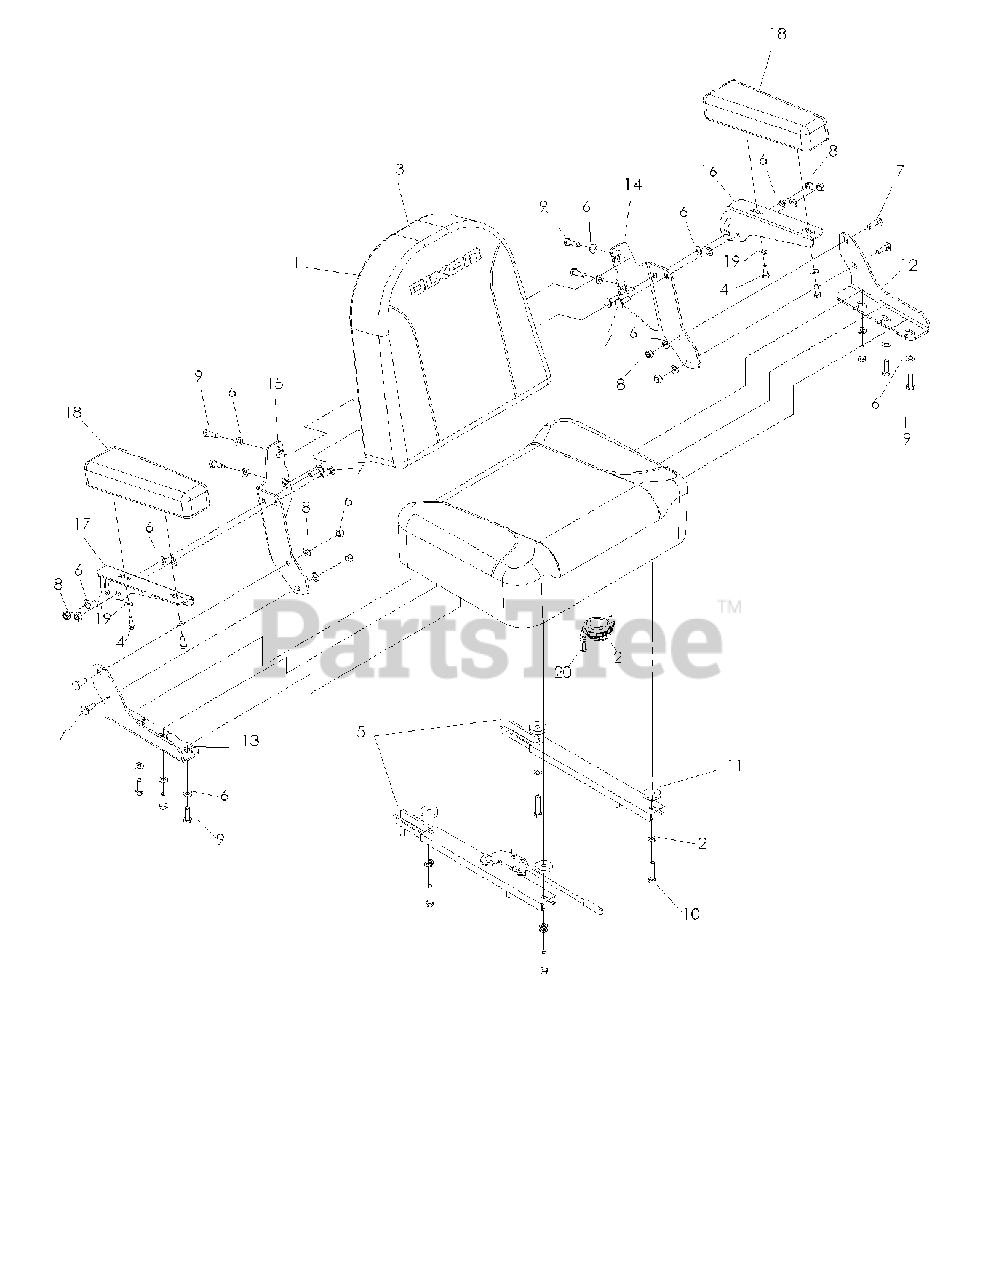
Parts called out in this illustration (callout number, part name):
1	SEAT ASM W/SLIDE
2	WASHER 5/16 LOCK
3	SEAT BACK
4	HCS 1/4C X 3/4 HCS
5	SEAT SLIDE (SET)
6	FLAT WASHER 5/16 SAE
7	RHSNB 5/16C X 1
8	NUT 5/16 NYLOC
9	5/16-18X1 HHB G5W/NY
10	5/16-18X1-1/2 HHB GR5WNY
11	WASHER NYLON
12	SEAT BOTTOM BRKT LH
13	SEAT BOTTOM BRKT RH
14	SEAT BACK BRKT LH
15	SEAT BACK BRKT RH
16	ARM REST BRACKET LH
17	ARM REST BRACKET RH
18	ARMREST
19	WASHER 1/4 SAE
20	SCR 1/4-20X3/4 SLTD RDHD GR2ZD
21	SEAT SWITCH KIT
